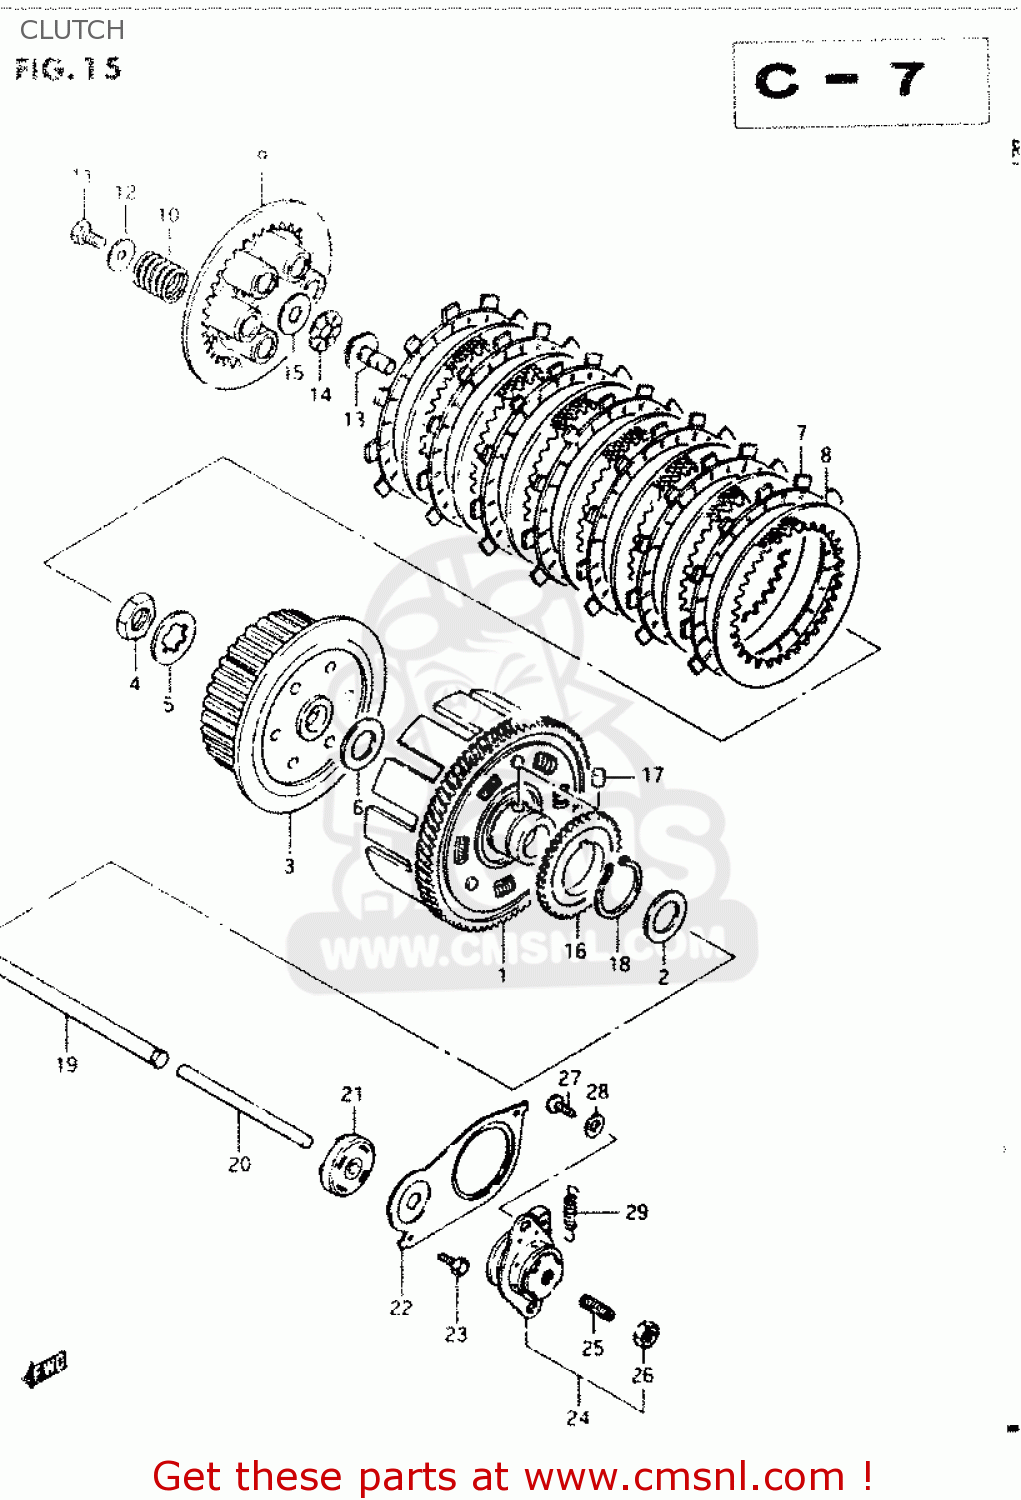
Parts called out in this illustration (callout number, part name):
1	GEAR ASSEMBLY,PRIMARY DRIVE
2	WASHER
3	HUB,CLUTCH SLEEVE
4	NUT (20MM)
5	WASHER,LOCK
6	WASHER(20X44X3)
7	PLATE,CLUTCH DRIVE (MCA)
8	PLATE,CLUTCH DRIVEN (NAS)
9	DISC,CLUTCH PRESSURE
10	SPRING
11	BOLT, UPPER
12	WASHER
13	PIECE,CLUTCH PUSH
14	BEARING(15X28X2)
15	WASHER
16	GEAR,OIL PUMP DRIVE
17	PIN(6X6)
18	CIRCLIP
19	ROD,PUSH,R
20	ROD,CLUTCH PUSH
21	SEAL,OIL(6X34X10)
22	PLATE,CLUTCH PUSH ROD
23	BOLT
24	SCREW ASSY,CLUTCH RELEASE
25	SCREW(6X25)
26	NUT 6MM
27	SCREW
28	WASHER
29	SPRING
